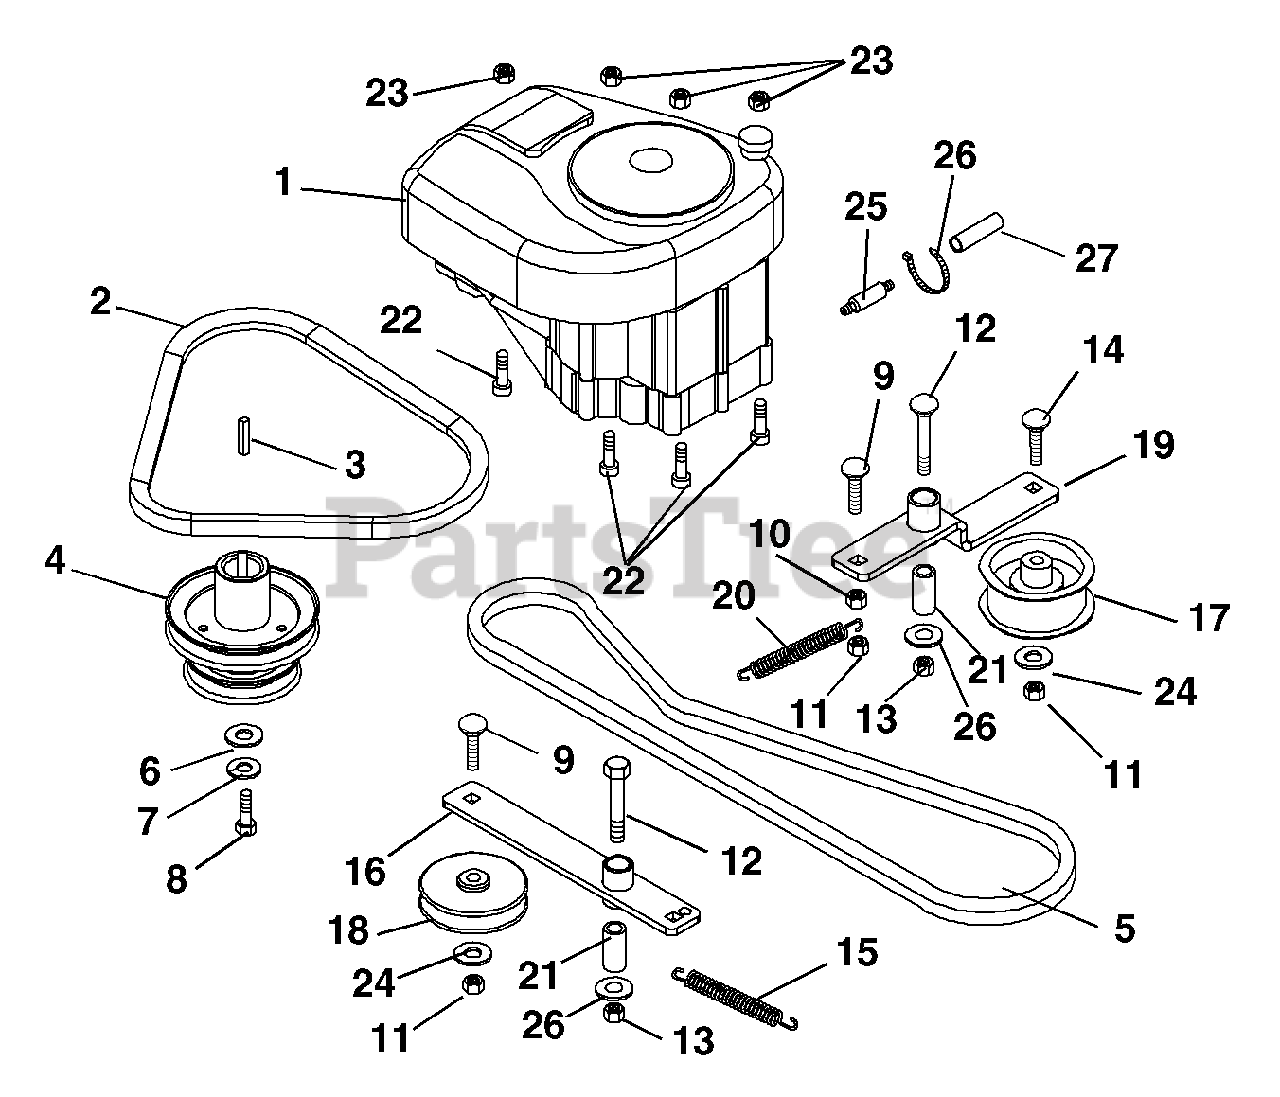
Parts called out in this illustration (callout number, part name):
1	Group, Engine 12HP Intek (062)
1	Group, Engine 10HP Intek (060)
1	Group, Engine 14HP Intek (064)
2	V-Belt 4L-Section 30.219 x .547
3	Key, Straight .25 x 1.75 x .25
4	Stack, Sheave (060, 062)
4	Stack, Sheave (064)
5	Belt, PTO (062)
5	Belt, PTO (060)
5	Belt, PTO (064)
6	Washer, Flat Steel .463 x 1.375 x .25
7	Washer, Locking .44 x .109 Regular
8	Bolt, Hex .44-20 x 1.75 Grade 5
9	Bolt-Round Head Square Neck .38-16 x 1.25 Grade 5
10	Nut-Flange .375-16
11	Nut, Locking Top Flange .38-16
12	Bolt, Hex .50-13 x 2.25 Grade 5
13	Nut, Locking Nylock Thin .50-13
14	Bolt-Round Head Square Neck .38-16 x 2.00 Grade 5
15	Spring, Tension .095 x .50 x 5.50
16	Idler, Drive
17	Sheave 3.25 x 1.25
18	Idler, V 3 x .38
19	Idler, 32"Deck PTO (060, 062)
19	Idler, 40" Deck PTO (064)
20	Spring, Extension.093 x .75 x 4.00
21	Bushing-Sleeve .50 x .75 x 1.56
22	Screw, Socket Head Button Head .31-18 x 1.50 Grade 8
23	Nut-Locking-Top-Flange .31-18
24	Washer-Flat-Steel .38 x .875 x .083
25	Valve, Oil Drain
26	Cable Tie
27	Tube, Oil Drain
28	Washer-Flat-Steel .563 x 1.38 x .109
